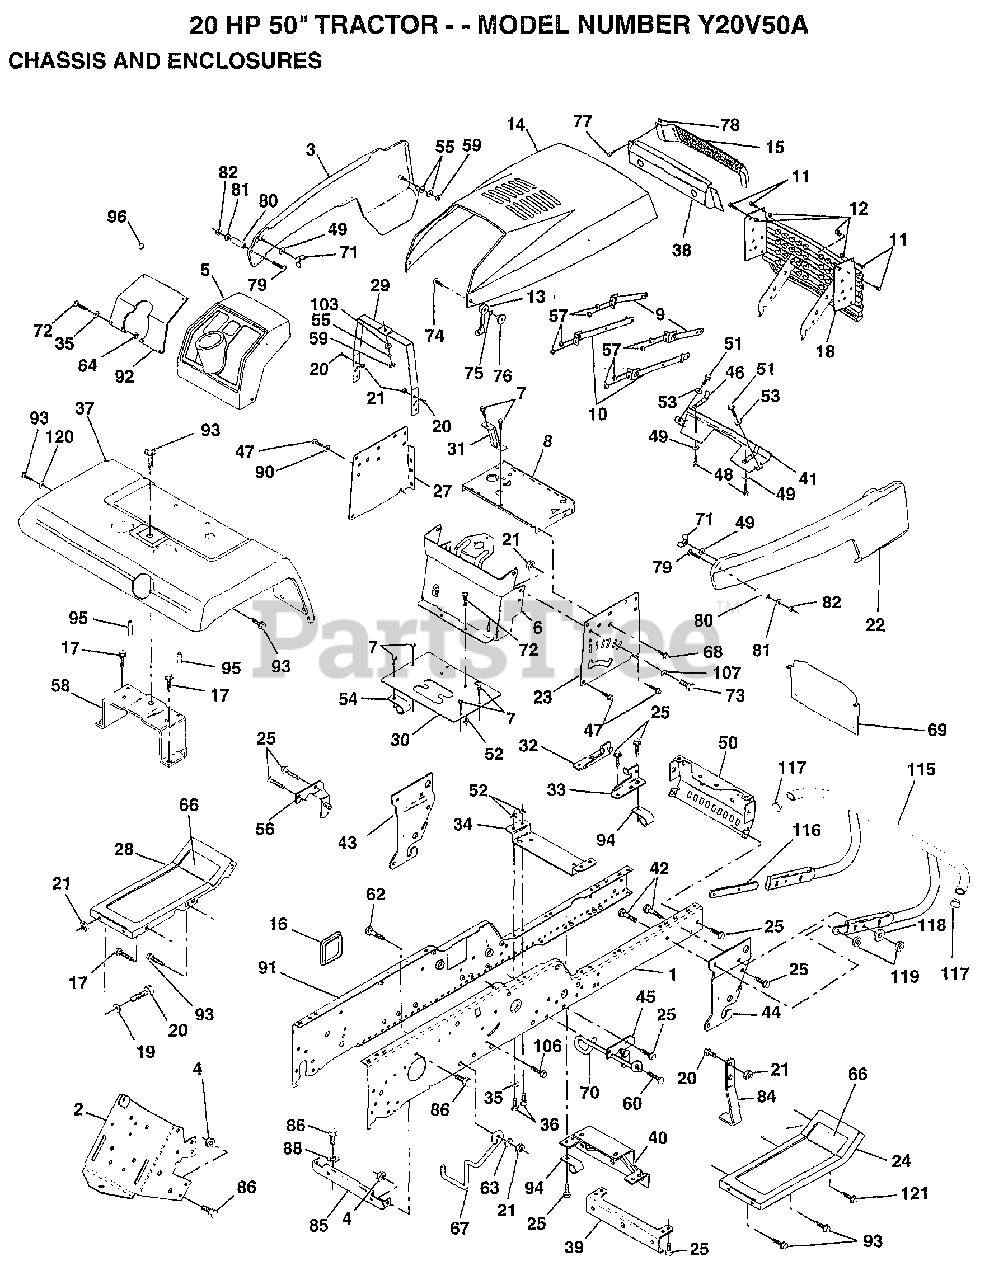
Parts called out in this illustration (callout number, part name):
2	DRAWBAR GT
4	NUT.7/16
5	DASHBOARD BLACK
6	DASH ASM LOWER
7	SCREW
8	SUPPORT BATRY VGT
12	NUT
13	HOOD LATCH T
15	LENS LT
16	COVER ACCESS
17	SCREW
19	WASHER
20	BOLT
21	NUT
22	PANEL SIDE RH
25	SCREW
29	SUPPORT ASS'Y
30	SADDLE SILKSCRN
31	BRACE.SUPT.STRG
32	BRACKET ASM FRAME
33	BRACKET ASM FRAME
34	BRACKET.ENG.SUPT.
35	WASHER
36	BOLT
37	FENDER
39	BRACKET.AXLE.FRT.
42	BOLT.3/8-14X1.25
43	BRACKET.SUS.FT.LH
44	BRACKET.SUS.FT.RH
47	SCREW LT
48	SCREW
49	WASHER
50	BRACKET.CHASSIS.
51	SCREW HEX CRT
52	NUT
53	WASHER
54	"CLIP,INSULATOR"
55	WASHER PM
57	NUT
58	BRKT.ASM.FENDER
60	SCREW
62	BOLT D
63	WASHER
66	FOOTREST PAD
67	GUIDE BELT TRANS
68	SCREW LT
69	SHIELD.HEAT.VGT.
70	GUIDE.BELT.MID.SP
72	SCREW
73	BOLT
74	SCREW
75	LOCKWASHER
76	WELDNUT
77	"""J"" FASTENER LT"
79	SCREW
80	SPACER LT
81	WASHER
84	STOP.OVER.CENTER
86	BOLT
88	LOCKWASHER
90	LOCKWASHER
92	PLATE YP SLKSCR
93	SCREW LT
94	CLIP GTV
95	NUT-PUSH YT
96	PLUG-DASH T
103	LOCKWASHER
106	BOLT.5/16-18X1.25
107	WASHER
115	BUMPER.ASM.W/PY
116	BRACKET.EXT.BUMP.
117	PLUG.PLASTIC
118	WASHER
120	WASHER HYT
121	SCREW GTV
